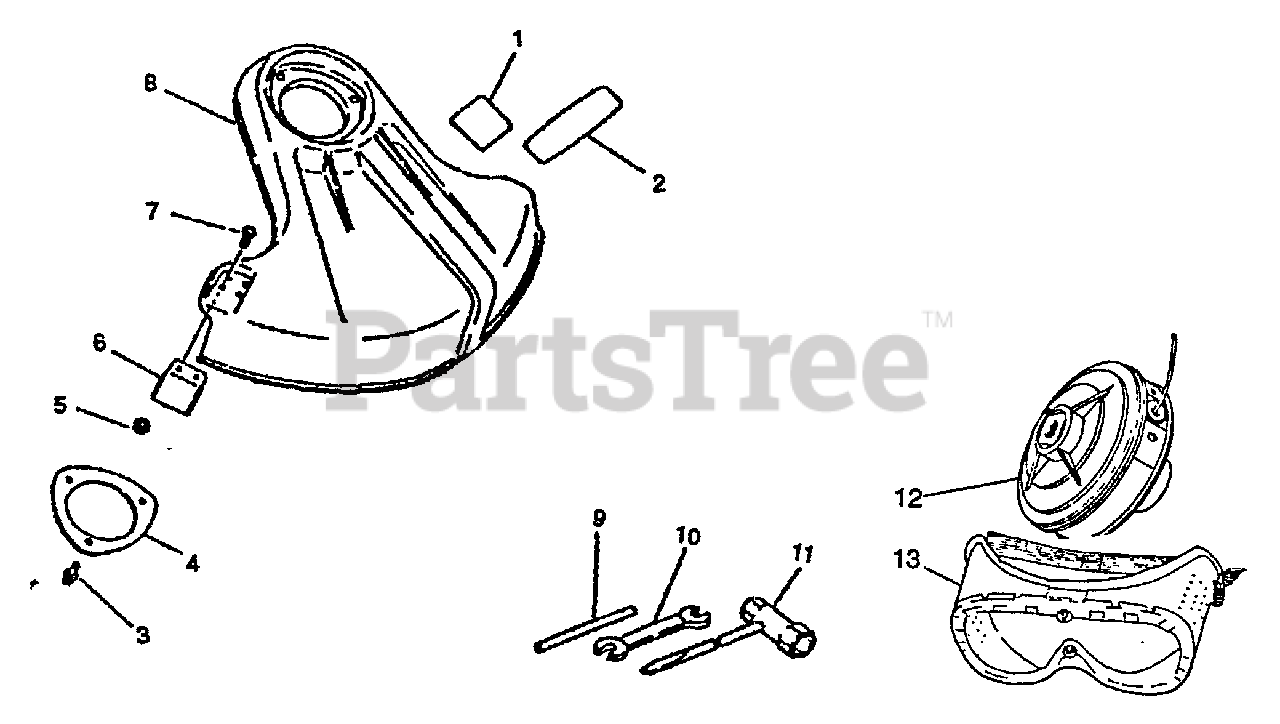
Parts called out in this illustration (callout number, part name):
1	Label, Caution
2	Label, Echo
3	Screw 5X16
4	Bracket, Shield
6	Knife, Cord
7	Screw 5X16
9	Locking Tool
10	Spanner 8X10
11	Wrench, W/Screwdriver
12	Cutter Asy, Line
